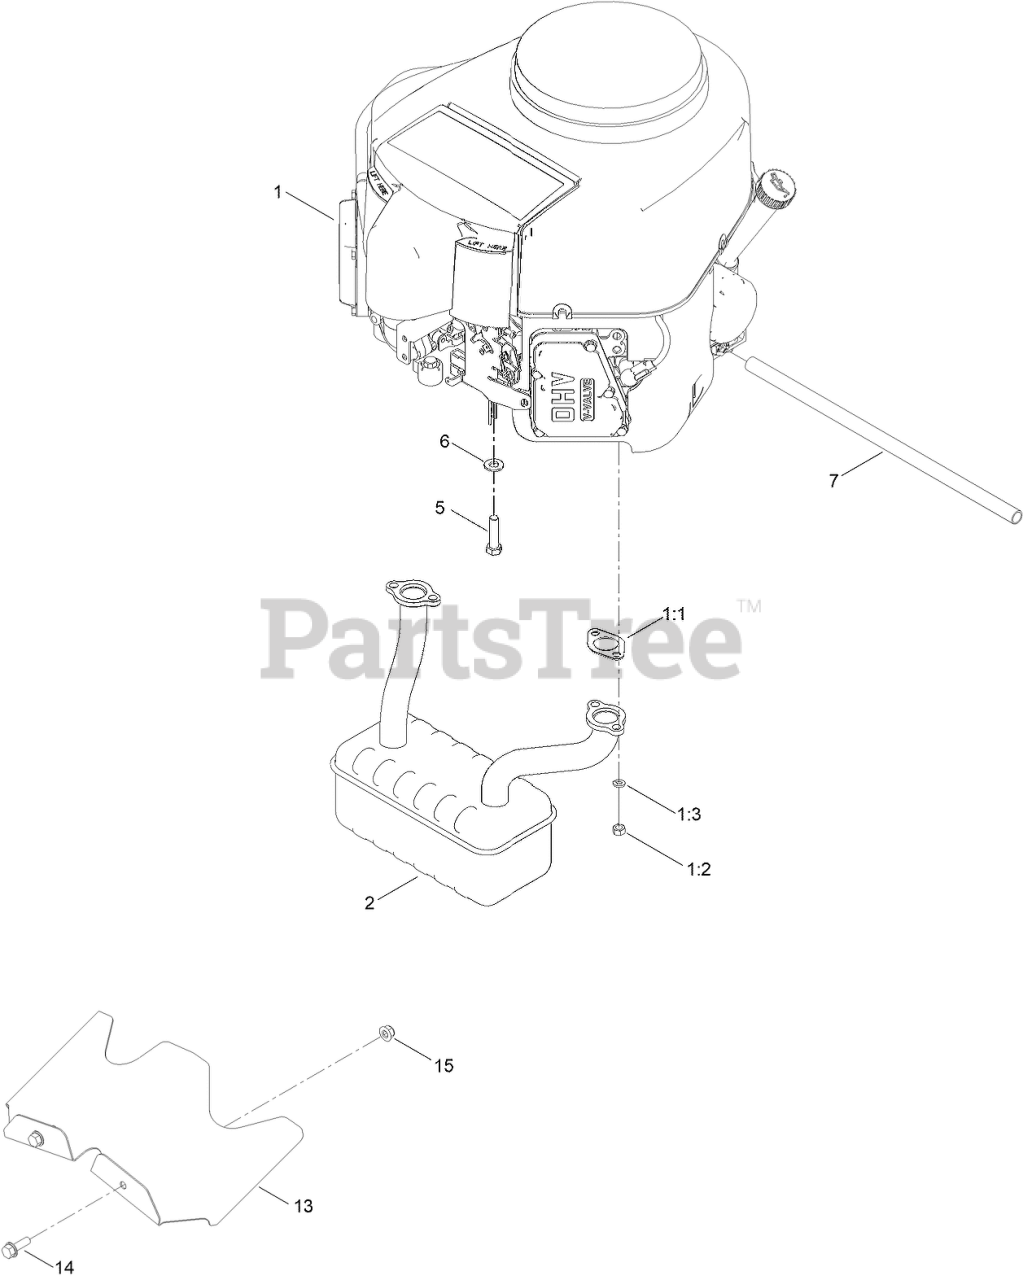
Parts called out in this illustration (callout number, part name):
1:1	GASKET-EXHAUST
1:3	WASHER-LOCK
2	MUFFLER
5	BOLT-HH
6	WASHER-FLAT
7	TUBE-DRAIN, OIL
13	SHIELD-HEAT
14	SCREW-HHF
15	NUT-HF, NI
